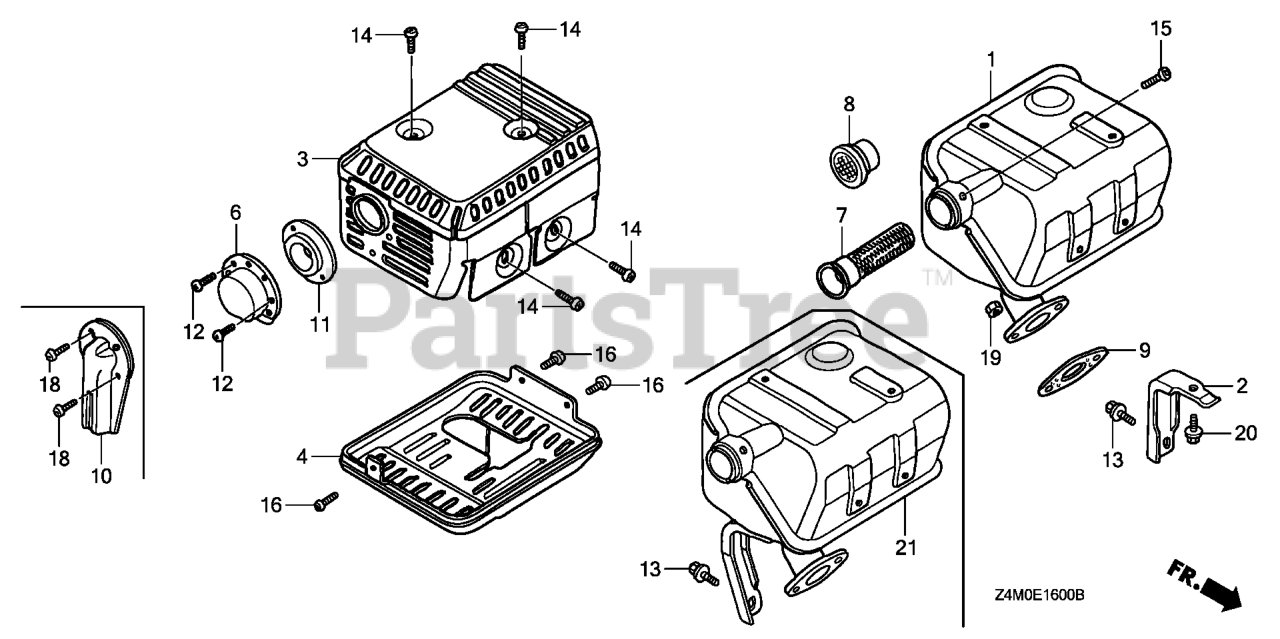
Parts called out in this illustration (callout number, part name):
1	MUFFLER
1	MUFFLER (ARRESTER)
3	PROTECTOR, MUFFLER (STD)
7	ARRESTER, SPARK
9	GASKET, MUFFLER
14	SCREW, TAPPING (5X8)
15	SCREW, TAPPING (4X6) (TO INSTALL OPTIONAL SPARK ARRESTER)
19	NUT, HEX. (8MM)
